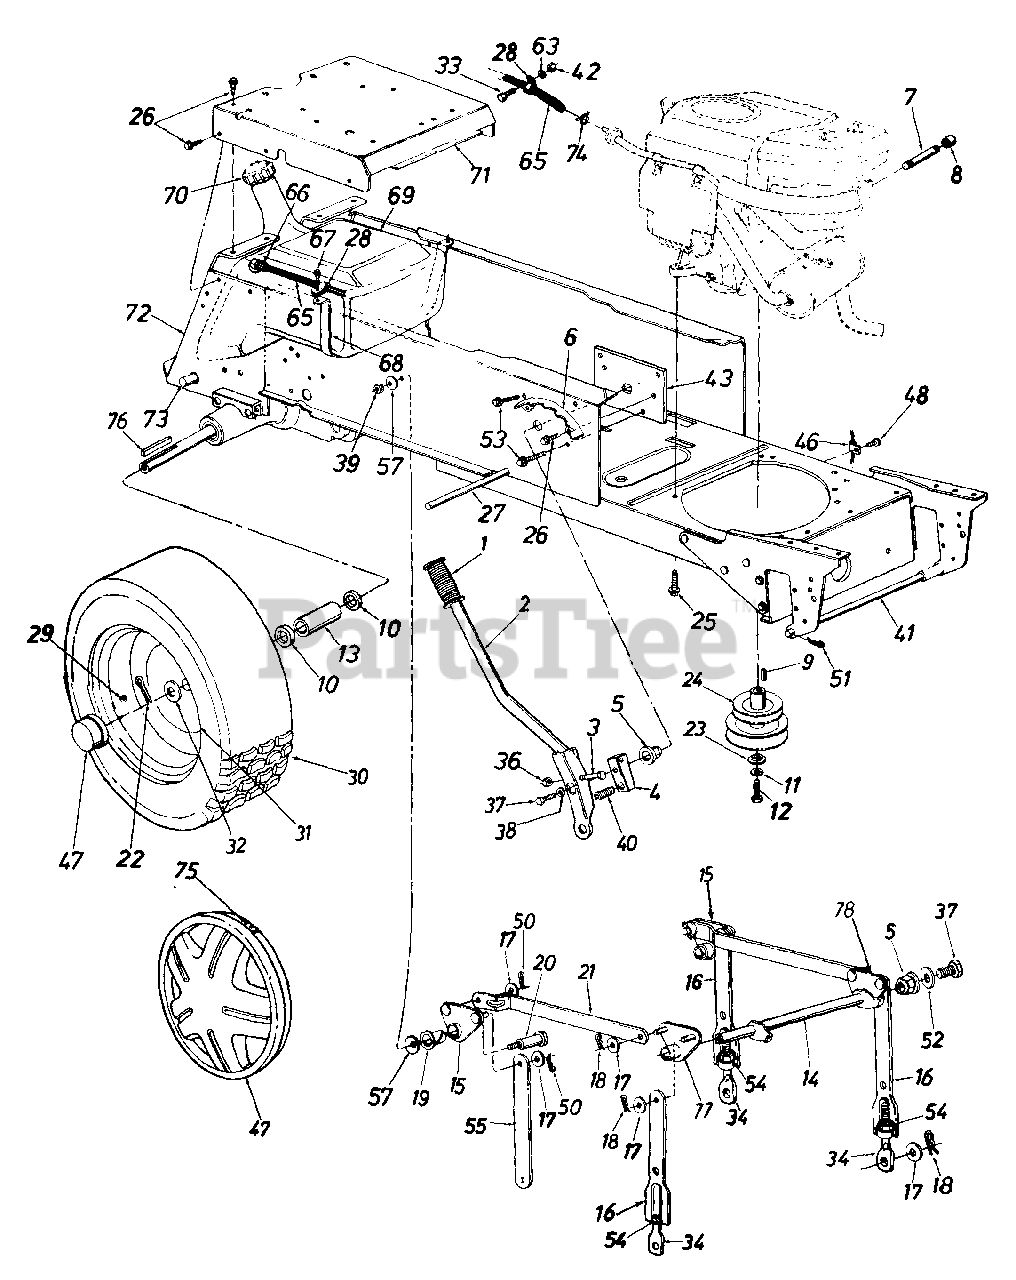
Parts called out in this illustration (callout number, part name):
1	Grip
4	Lift Shaft Drive
5	Plastic Hex Brg. 5/8" I.D.
8	Pipe Cap 3/8-18 Npt.
9	Sq. Key 1/4" x 1/4" x 1.50" Lg.
10	Fl-Wash. 1.03" I.D. x 1.62" O.D.
11	L-Wash. 7/16" I.D.
12	Hex Scr. 7/16-20 x 1.50" Lg.
13	Spacer 1.0" I.D. x 1.25" O.D.
14	Lift Shaft Ass'y.
15	Lift Pivot Brkt. Ass'y.
17	Fl-Wash. 1/2" I.D. x 1.00" O.D. x .090"
18	Hairpin Cotter
19	Nyliner 5/8" I.D. x .88" Lg.
20	Shld. Bolt 5/8" Dia. x .96" Lg. 3/8-16
23	Flat Wash. .44" I.D. x 1.25" O.D. x .17"
24	Two-Step Engine Pulley
25	Hex Wash. Hd. Scr. 3/8-16 x 1.25" Lg.
26	Hex Thd. Rolling Scr. 5/16-18 x .75" Lg.
27	Running Board Rod
28	Clamp
29	Air Valve
30	Rear Wheel Ass'y. Comp.
33	Hex Bolt 1/4-20 x .62" Lg.
34	Eye Bolt Adj. Link 1/2-13 Thd.
36	Hex Cent. L-Nut 5/16-18 Thd.
37	Hex Bolt 5/16-24 x 62" Lg.
38	L-Wash. 5/16" I.D
39	Hex Top L-Nut 3/8-16 Thd
40	Compression Spring
41	Deck Connecting Rod
42	Hex Nut 1/4-20 Thd.
47	Hub Cap
48	Hex Wash. Hd TT-Tap Scr 1/4-20 x 5" Lg
50	Cotter Pin .09 Dia. x 1.0" Lg.
51	Int. Cotter Pin
52	Flat Wash 34" I.D. x 1.12" O.D. x .125"
53	Hex Wash Hd. AB-Tap Scr. 5/16-24 x 5" Lg.
54	Hex Nut 1/2-13 Thd.
57	Bell-Wash .4" I.D. x 1 13" O.D.
63	L-Wash. 1/4" I.D
65	Fuel Line 46" Lg.
66	Hose Clamp
67	Hex AB-Tap Scr 1/4 x 62" Lg
68	Fuel Tank Strap
69	Gas Tank
70	Gas Gauge
71	Seat Plate
74	Hose Clamp
75	Spring Clip
76	Sq. Key 1/4" x 3" Lg.
77	Pivot Brkt. Ass'y.- R.H
78	Pivot Brkt. Ass'y - L.H.
